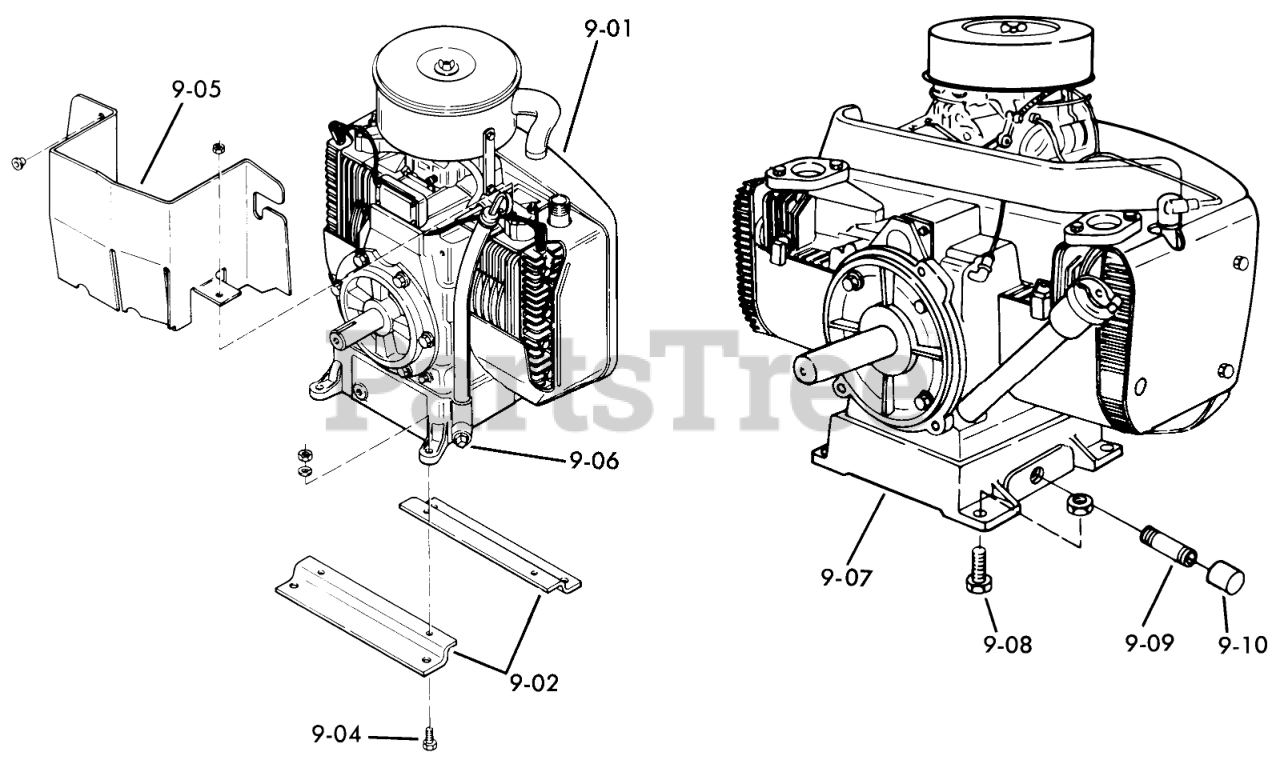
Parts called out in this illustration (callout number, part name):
9-01	Engine-16 HP Onan
9-02	Bracket-Engine
9-03	Bolt
9-04	Bolt
9-04	WASHER 5/16 SAE
9-05	Heat Shield
9-06	ELBOW
9-07	Engine 19.9 HP Kohler
9-08	Hhcs
9-08	Nut
9-09	Nipple 3/4 Pipe X2
9-10	Cap-3/4 Pipe
